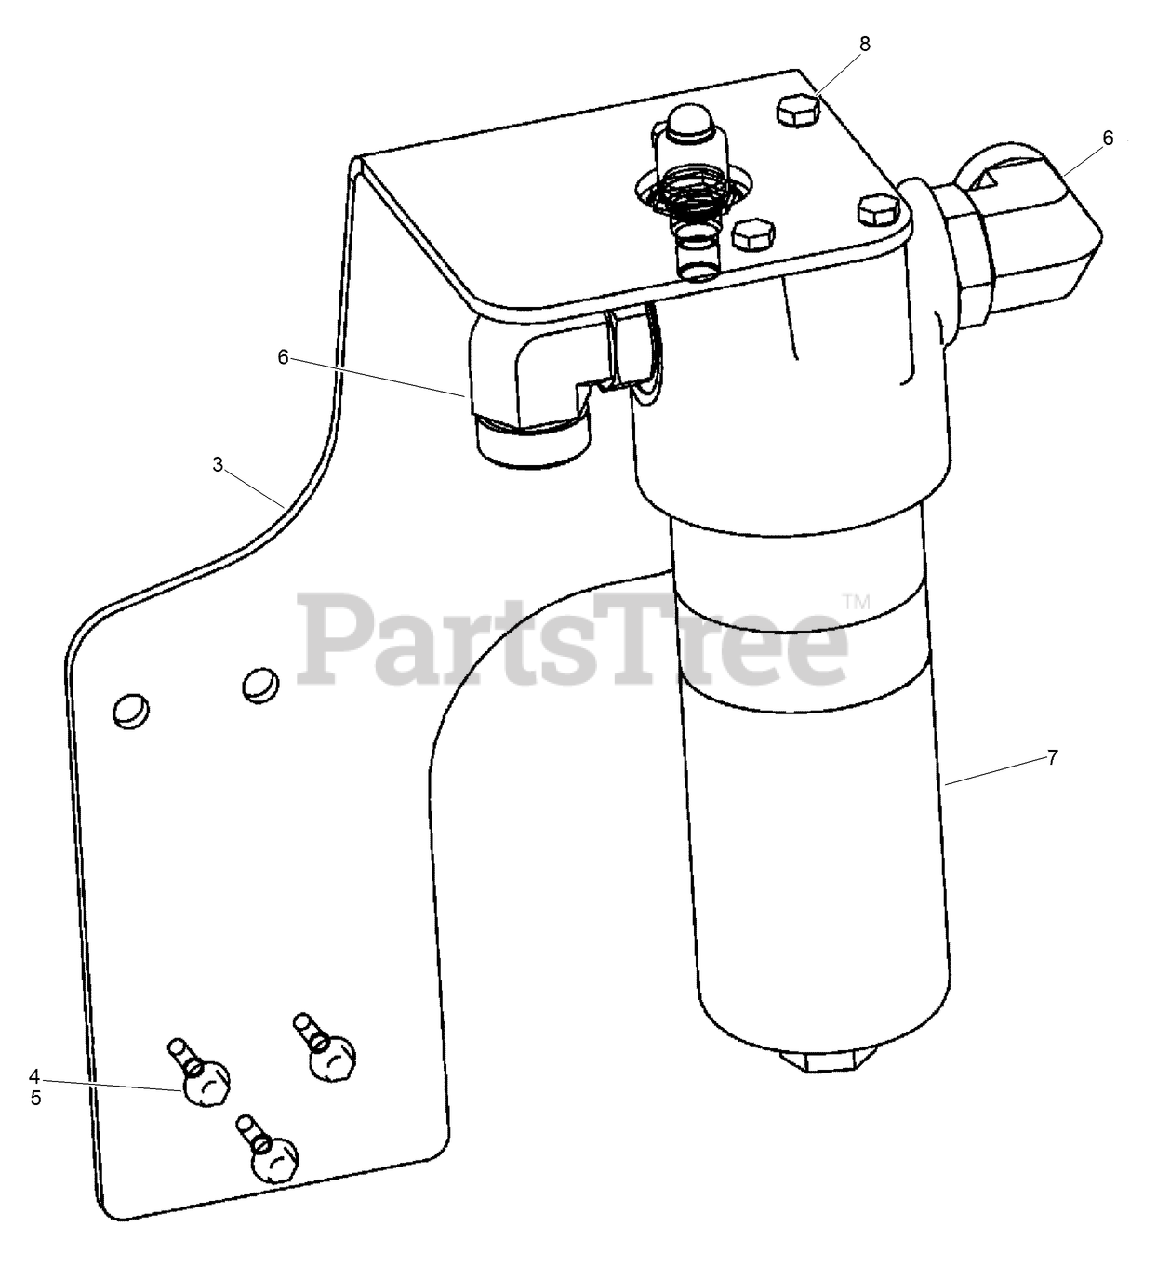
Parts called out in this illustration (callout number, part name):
3	ASSEMBLY - Filter Mount
4	SCREW, METRIC FLANGE w/BODY - M8 x 35
5	NUT-TORQUE, PREVAILING
6	CONNECTION - 90 Deg, -20 ORFS / -20 ORB
7	FILTER-HYD, HIGH PRESSURE
8	SCREW-HH
